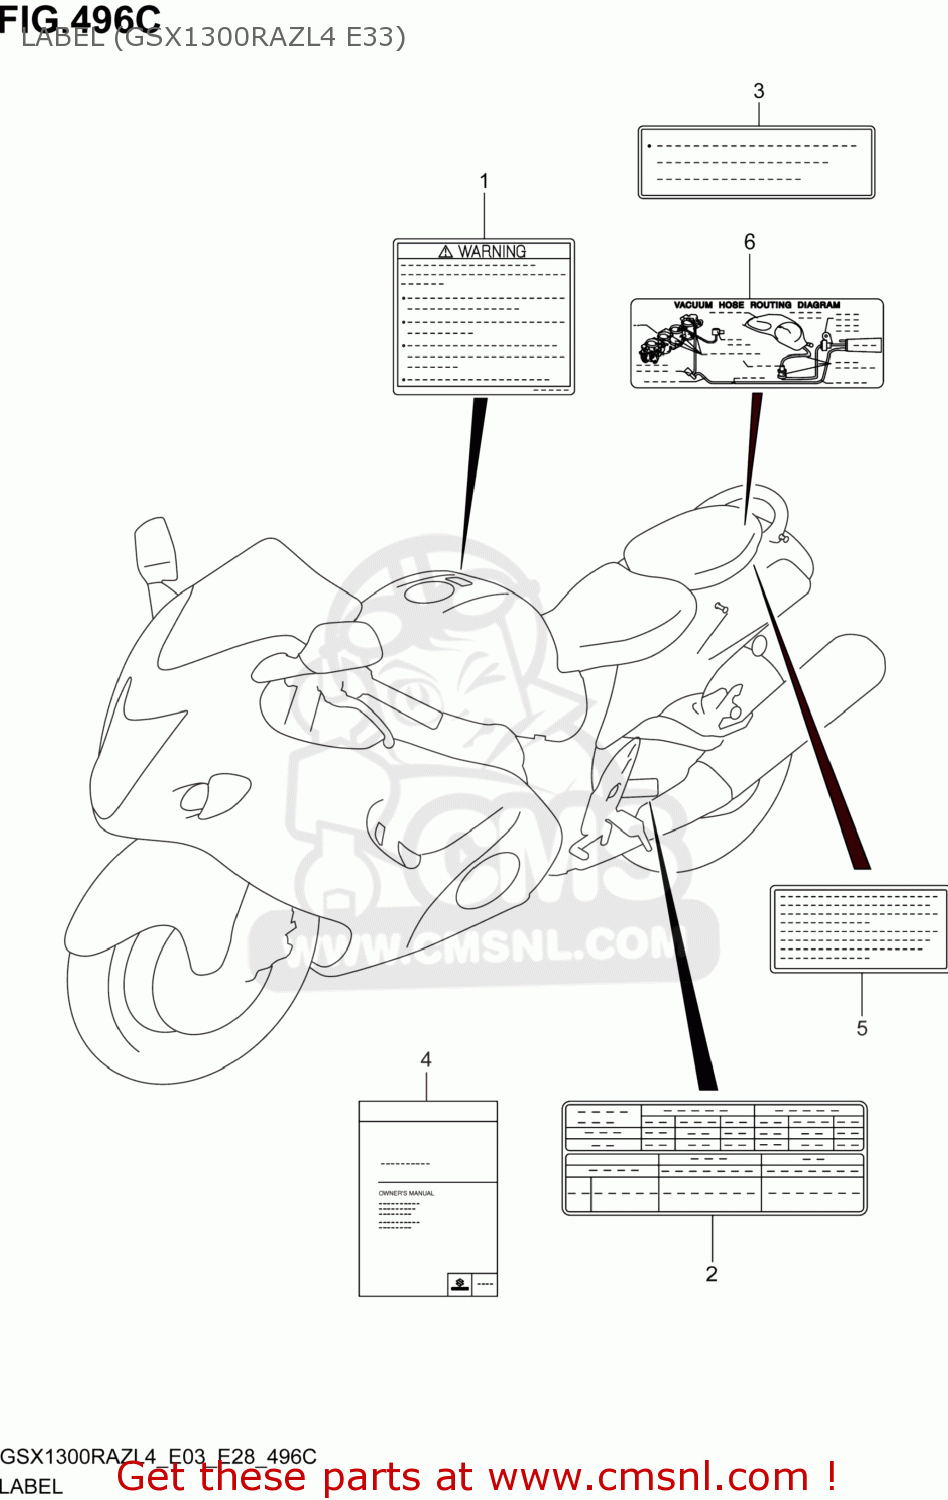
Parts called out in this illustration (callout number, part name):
1	LABEL,GENERAL WARNING
2	LABEL,TIRE INFORMATION
3	LABEL,FUEL INFORMATION
4	MANUAL,OWNER'S
5	LABEL,MANUAL NOTICE
6	LABEL,VACUUM HOSE ROUTING
